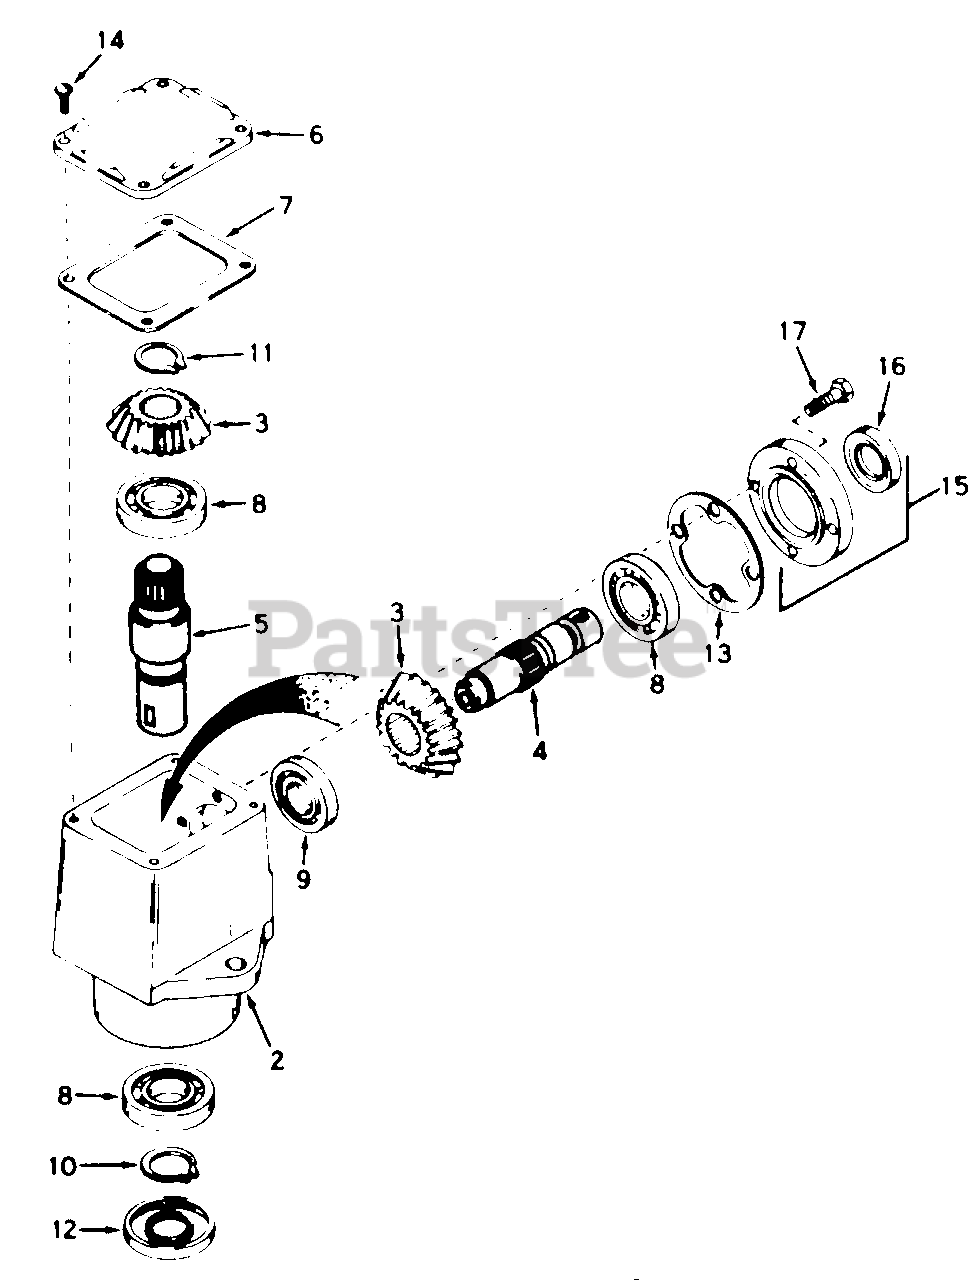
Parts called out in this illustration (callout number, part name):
1	FOOT, right hand
2	Housing, Right Angle Drive
2	FOOT, left hand
3	Gear, Miter
3	GUARD, FOOT POCKET, right hand
4	Shaft, Input
4	GUARD, FOOT POCKET, left hand
5	Shaft, Output
5	FRAME, FRONT PANEL
6	Cover, Left-Hand
6	BRACE, FRONT PANEL FRAME
7	Gasket, Cover
7	SUPPORT, CHUTE CONTROL CRANK
8	Bearing, Ball
8	BRACKET, REAR ATTACHING, right hand
9	Bearing, Ball
9	BRACKET, REAR ATTACHING, left hand
10	Ring, Snap
10	PLATE, REAR ATTACHING
11	Ring, Snap
11	CROSS BAR, REAR
12	Seal, Oil
12	POST, FRONT, right hand (straight w/screw)
13	Gasket, Cap
13	POST, FRONT, left hand (straight w/screw)
14	Screw, Rd. Hd., Self Tap, 10-24 x 1/2
14	BRACE, TOP, right hand
15	Cap and Seal Assembly, Retainer (Includes Nos. 16 & 17)
15	BRACE, TOP, left hand
16	Seal, Oil
16	TOP FRAME, HTS
17	Screw, Hex Hd., 1/4-10 x 1
17	POST, REAR CORNER, right hand
18	POST, REAR CORNER, left hand
19	"L" BRACKET
20	3/4" LOOP
21	FRONT PANEL VINYL
22	WINDSHIELD
23	DOOR, right hand
24	DOOR, left hand
25	REAR CURTAIN
26	TOP, FIBERGLASS, HTS (trim)
27	CRANK, CHUTE CONTROL
28	PARTS BAG (contents listed below)
29	1/4"-20 LOCKNUT
30	DOOR HINGE
31	1/4"-20 x 3/4" BOLT
32	SPRING, DOOR LATCH
33	1/4" FLAT WASHER
34	5/16"-18 x 1-1/2" BOLT
35	3/8"-16 LOCKNUT
36	3/8"-16 x 3/4" BOLT
